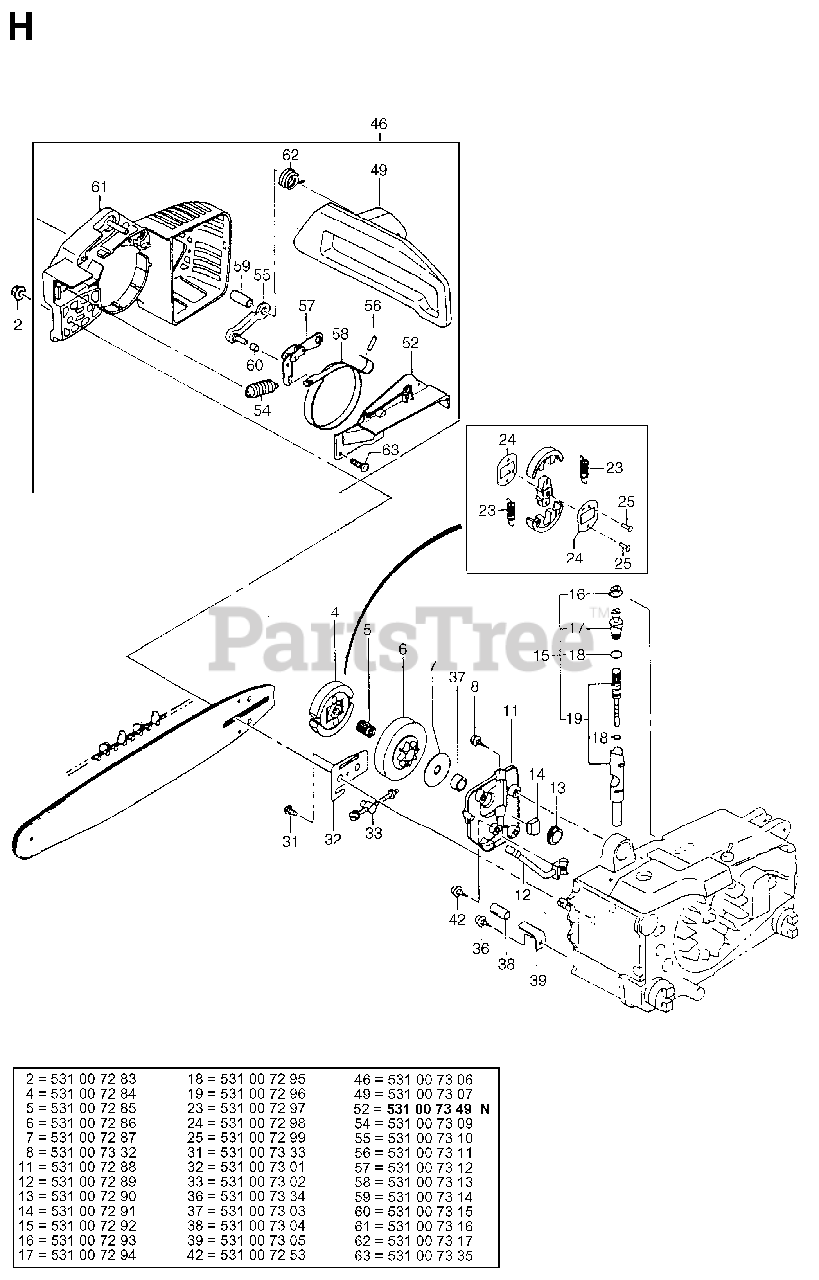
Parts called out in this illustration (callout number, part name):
5	NEEDLE BEARING
6	CLUTCH DRUM
14	PROTECTOR
19	PUMP PISTON
38	PROTECTOR
39	CHAIN CATCHER
46	CHAIN BRAKE
52	PROTECTOR
55	BRAKE LEVER
57	BRAKE LEVER
58	BRAKE BAND
